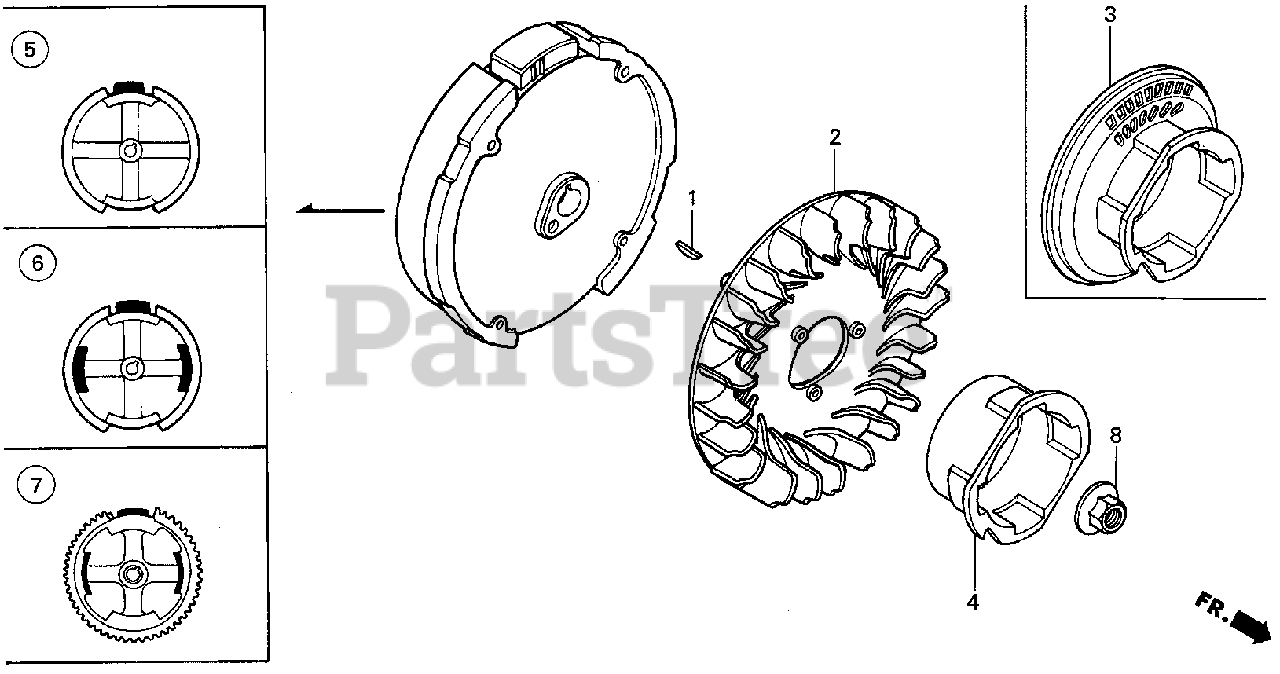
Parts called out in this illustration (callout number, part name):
1	KEY, SPECIAL WOODRUFF (25X18)
2	FAN, COOLING
4	PULLEY, STARTER
5	FLYWHEEL
5	FLYWHEEL (LAMP)
8	NUT, SPECIAL (14MM)
